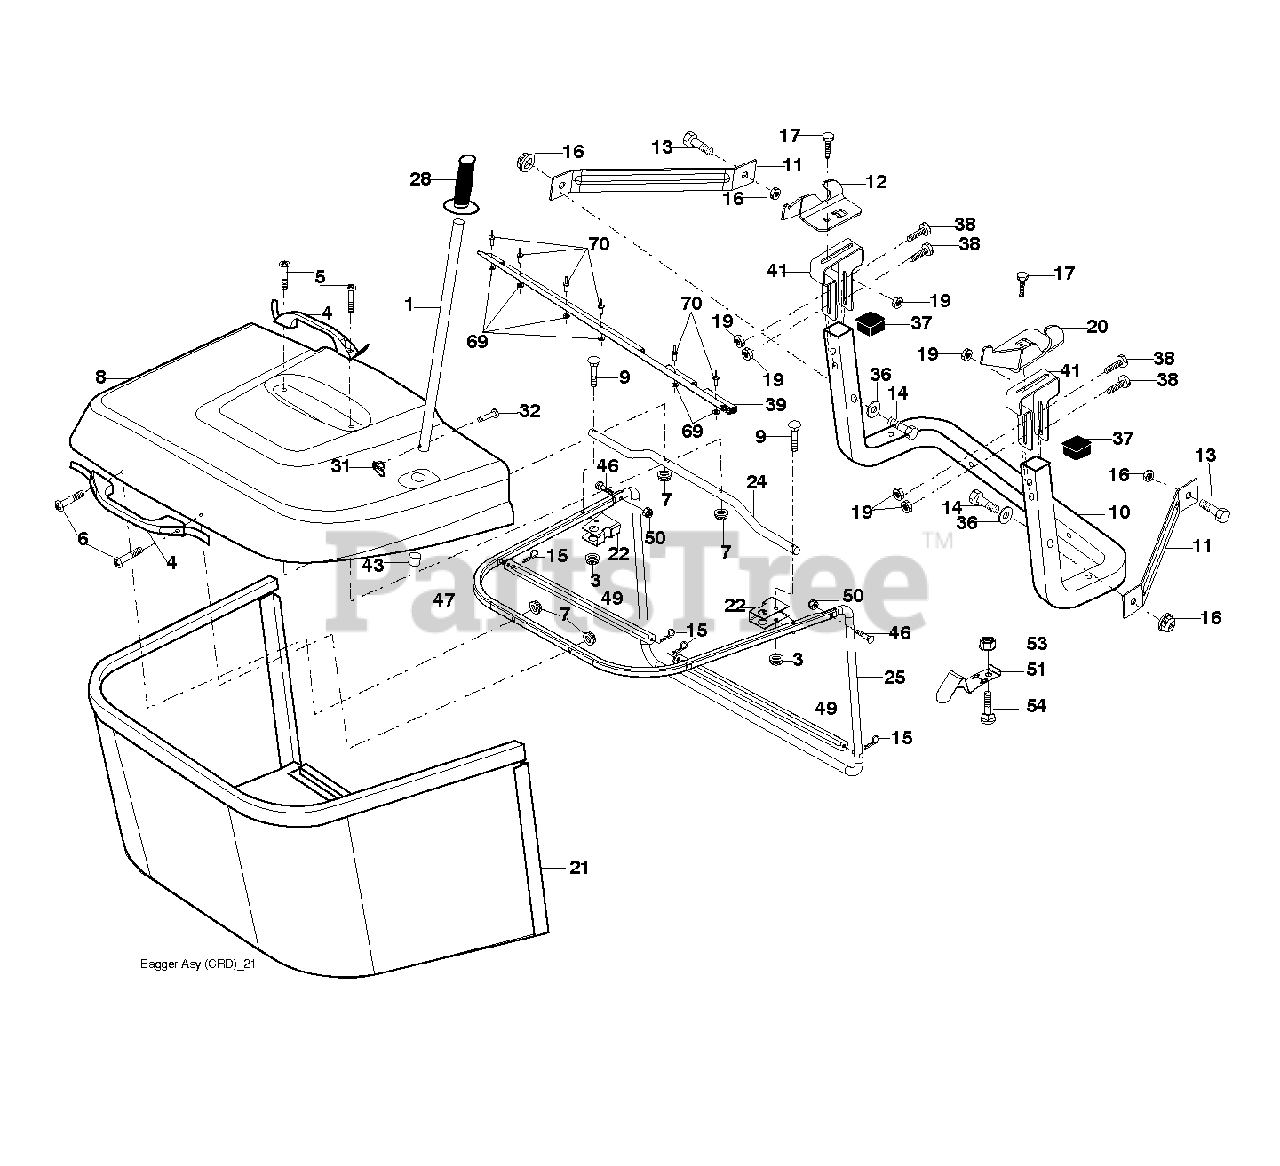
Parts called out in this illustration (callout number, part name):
1	TUBE.PNT.HDL.BAGGER.
3	NUT T
5	SCREW.PAN.HEAD
8	BAGGER.COVER.SEAL.ASM.CRD.428
11	BRACKET
14	BOLT-HEX EAK
15	RETAINER-SPRNG RB
16	NUT LOCK FLG 3/8-16 UNC
17	BOLT
19	NUT LOCK HEX FLANGE 5/16-18
20	BRKT.PIVOT.RH.CRD
21	BAGGER.ASM.CRD.2007
22	BRACKET.BAGGER.SD.
24	TUBE
28	GRIP.HANDLE.BLACK
31	RETAINER CLIP
32	RIVET,DRILLED
38	BOLT.5/16-18X2.5
39	SEAL.BAGGER.CRD
41	BRACKET.BAGGER.SD.
43	PLUG, TUBING END
46	BOLT.CARRIAGE.5/16-18
50	NUT.71038.31-18.HEX.NYLOCK
53	NUT
54	BOLT
